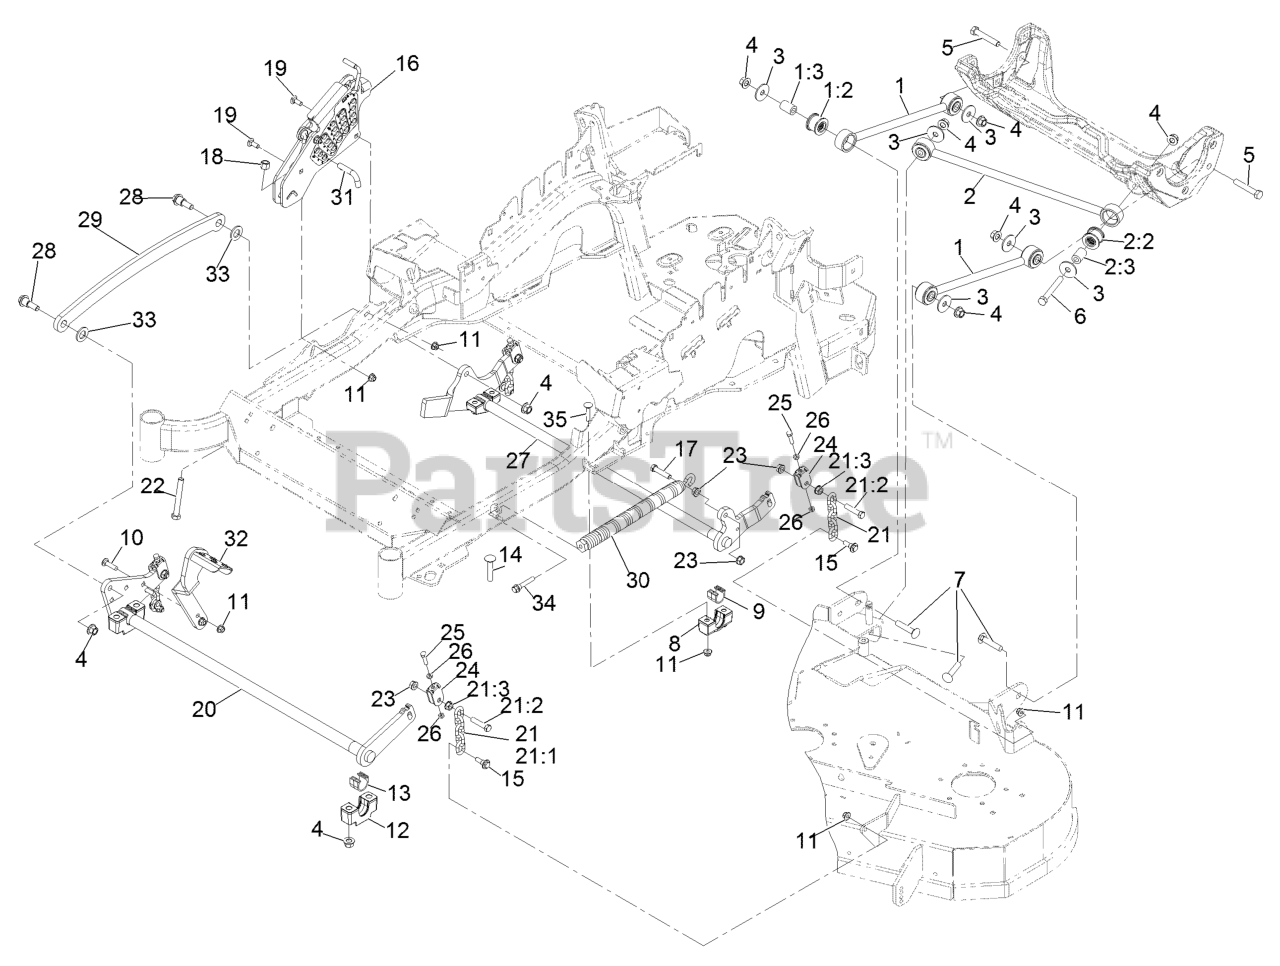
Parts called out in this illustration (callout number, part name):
1	DECK STRUT ASM
1:2	BUSHING-SUSPENSION, RUBBER
2	PANHARD ROD ASM
2:2	BUSHING-SUSPENSION, RUBBER
3	WASHER-THRUST
4	Nut-Lock 1/2-13
5	SCREW-HH
6	SCREW-HH
7	SCREW-CARR
8	SUPPORT-CROSS SHAFT, BEARING REAR
9	BEARING-CROSS SHAFT, REAR
10	SCREW-CARR
11	NUT-HF, NI
12	SUPPORT-CROSS SHAFT, BEARING
13	BEARING-CROSS SHAFT, FRON
14	Bolt-Carriage 1/2-13 X 2 1/2 Spl Neck
15	SCREW-SHOULDER, HHF
16	HOC ASM
17	SCREW-HH
18	NUT-LOCK, NI
19	BOLT-CARR
20	DECKLIFT-FRONT
21	DECK LIFT CHAIN ASM
21:1	CHAIN-LIFT, DECK
21:2	SCREW-HH
22	BOLT-TAP
24	YOKE-ADJUST, DECK
25	SCREW-HH
26	NUT-JAM
27	LIFT-DECK, REAR
28	SCREW-SHOULDER, HHF 1/2-13 X 1.12
29	LINK-LIFT, DECK
30	SPRING-EXTENSION
31	PIN-HOC
32	LEVER-FOOT
33	WASHER-FLAT
34	BOLT-SHOULDER
35	Bolt-Carriage 3/8-16 X 2 1/4
